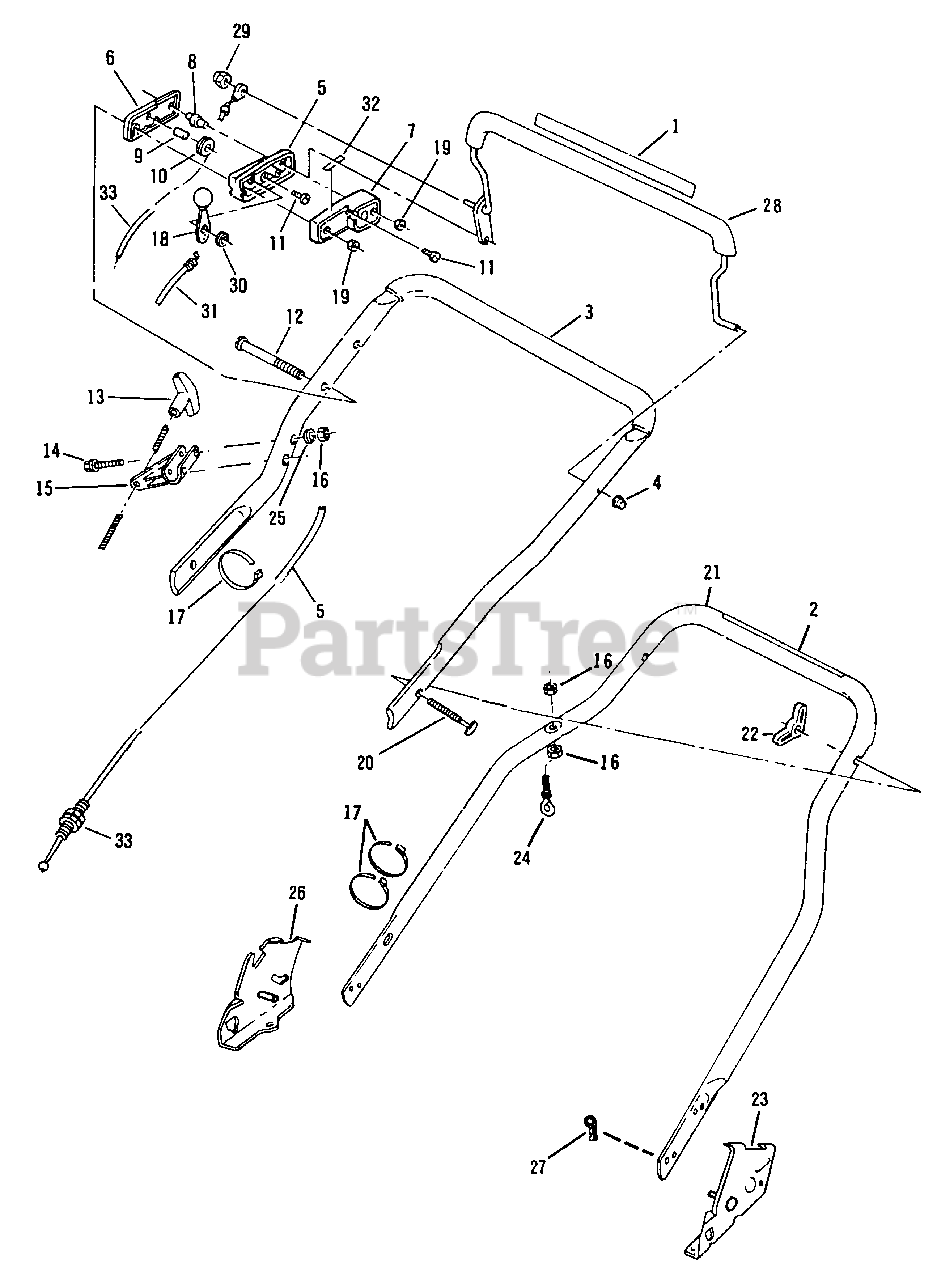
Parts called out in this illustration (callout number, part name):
1	Decal-Engine/Blade Control
2	Decal-Starting Instructions
3	Top Handle
4	Pushnut
5	Control Case-Center
6	Control Case-Outer
7	Control Case-Inner
8	Column
9	Pin
10	Pulley
11	Screw
12	Screw
13	Handle-Starter
14	Screw-Truss Head
15	Rope Guide Assembly
16	Locknut
17	Tie Strap
18	Lever and Knob Assembly
19	Nut-Hex-Centerlock
20	Screw
21	Handle-Bottom
22	Knob
23	Bracket-Handle-L.H.
24	Eyebolt
25	Washer
26	Bracket-Handle-R.H.
27	Hair Pin-Handle Bracket
28	Control Lever and Nut Assembly
29	Nut-Acorn
30	Washer-Spring
31	Cable-Throttle
32	Decal-Throttle
33	Control Cable Assembly
